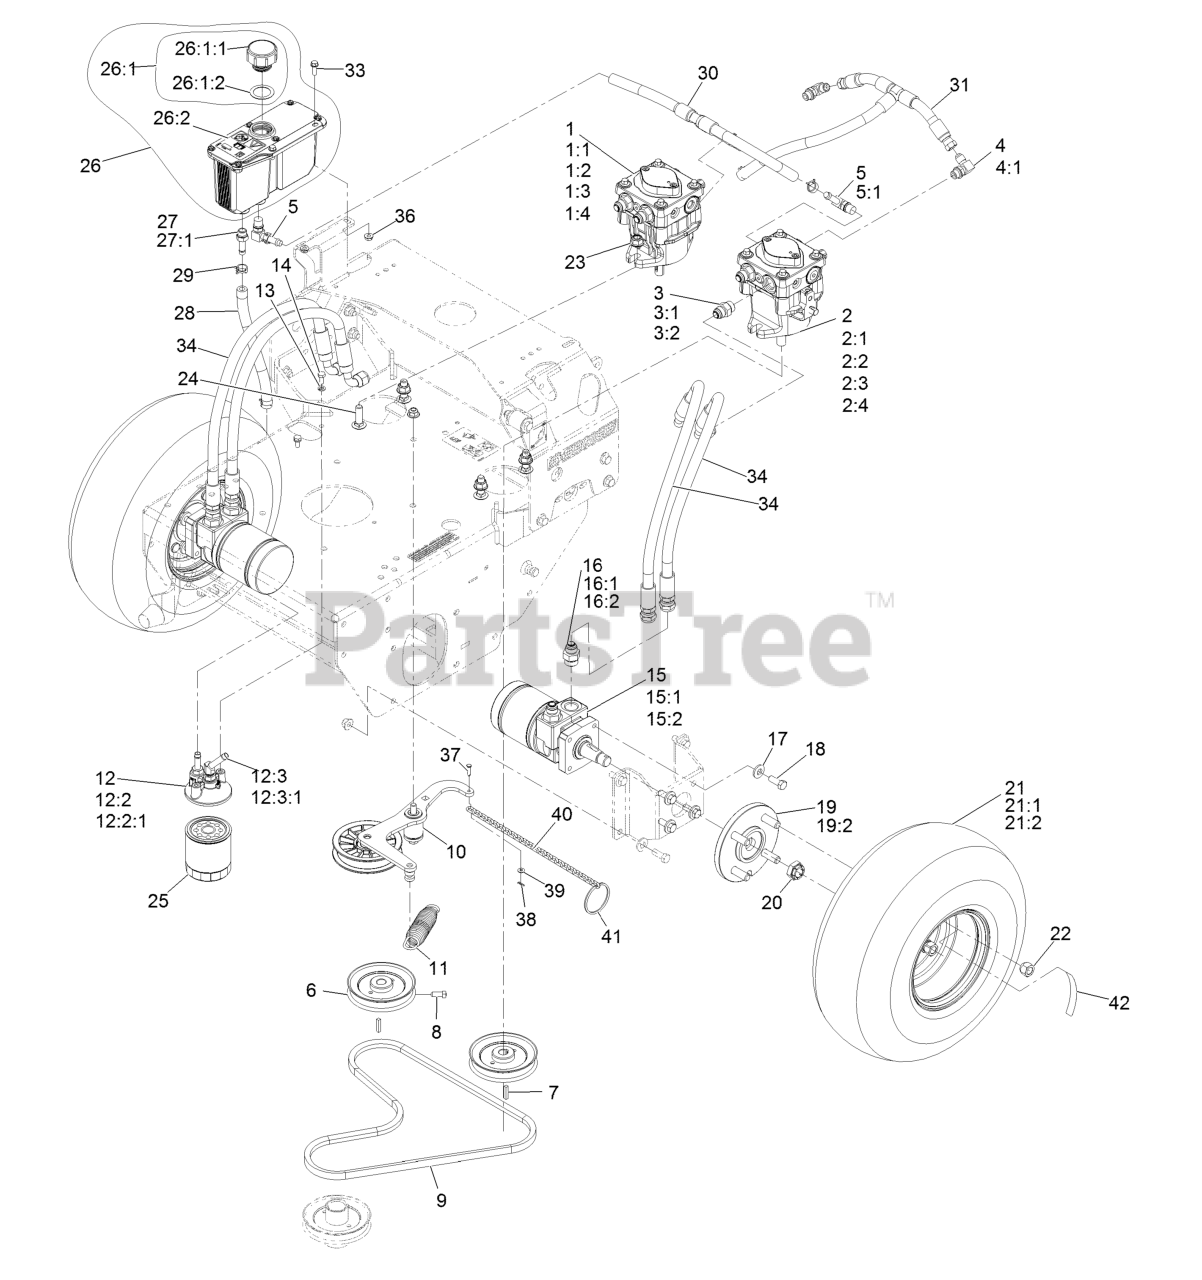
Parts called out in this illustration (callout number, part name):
1	RH HYD Pump ASM
1:1	Input Shaft Kit
1:2	Bearing-Thrust
1:3	Cylinder Block Kit
1:4	Seal Overhaul Kit
2	LH HYD Pump ASM
2:1	Input Shaft Kit
2:2	Bearing-Thrust
2:3	Cylinder Block Kit
2:4	Seal Overhaul Kit
3	Adapter-Straight
3:1	O-Ring-SAE #8
3:2	O-Ring-37 Flare #8
4	Fitting-Elbow, 90 DEG
4:1	O-Ring
5	Fitting-Elbow, 90
5:1	O-Ring
6	Sheave ASM
7	Key-5Mm X 5Mm X 25Mm
8	Screw-Set, SQH 5/16-18 X 3/4
9	Belt
10	ASM, Pump Idler
11	Spring-Extension
12	ASM, Filter Head
12:2	Adapter-Straight
12:2:1	O-Ring
12:3	Fitting-Barbed, 45 DEG
12:3:1	O-Ring
13	Washer-Lock 1/4 Heavy
14	Screw-HH 1/4-20 X 5/8
15	HYD Motor ASM
15:1	Seal Kit
15:2	Bearing And Seal Kit
16	Adapter-Straight
16:1	O-Ring
16:2	O-Ring-37 Flare #8
17	Washer-Spring Disc 3/8
18	Screw-HH 3/8-16 X 1
19	Wheel Hub ASM
19:2	Stud-Wheel
20	Nut-Lock
21	Wheel And Tire ASM
21:1	Tire-Turfmaster
21:2	Rim-Wheel
22	Nut-Lug 1/2-20
23	Nut-HF, NI
24	Bolt-Carriage 7/16-14 X 1 1/2
25	Element, Oil Filter
26	ASM, HYD Reservoir
26:1	Reservoir-HYD
26:1:1	Cap-Reservoir, HYD
26:1:2	Gasket-Cap
26:2	Decal-Warning
27	Adapter-Straight
27:1	O-Ring
28	Hose-Charge
29	Clamp-Hose 11/16
30	Hose-Case Drain
31	Hose-Charge
33	Screw-Machine 1/4-20 X 3/4
34	HYD Hose ASM
36	Nut-Whizlock 1/4-20
37	Pin-Clevis
38	Pin-Hair
39	Washer-Plain
40	Chain-Link, Twist
41	Ring-Split
42	Decal-Torque Wheel Lug-Hub
